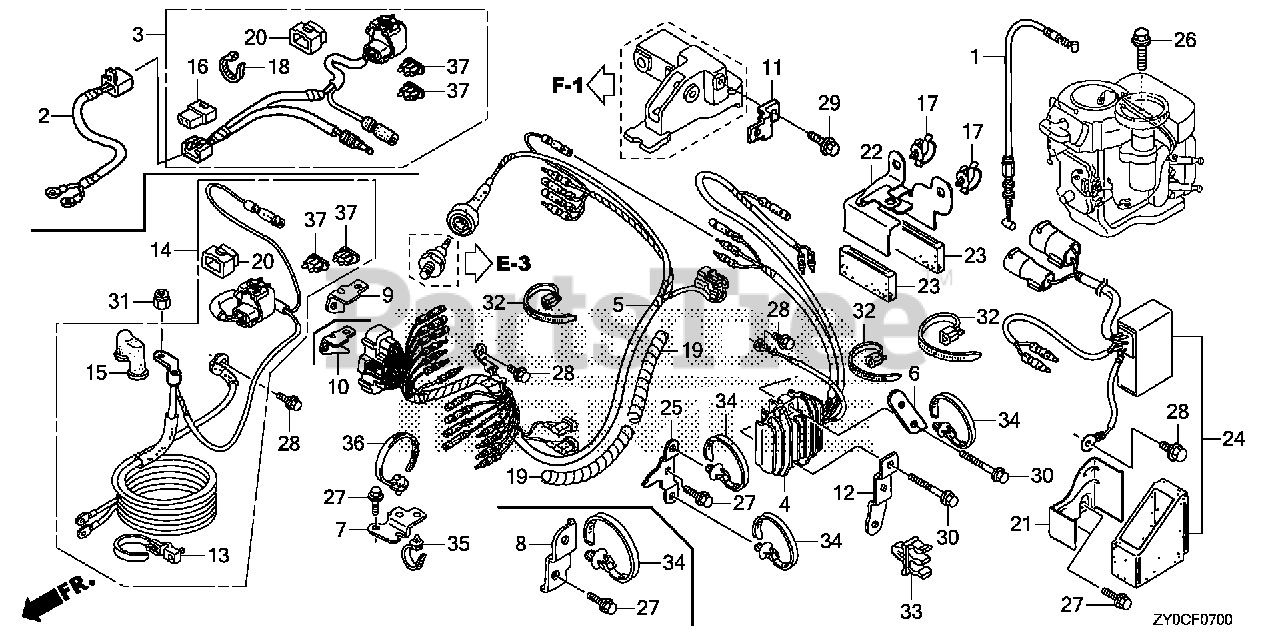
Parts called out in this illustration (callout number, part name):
1	CABLE, NEUTRAL STARTING
4	RECTIFIER ASSY., REGULATOR
5	WIRE HARNESS ASSY. (SELF STARTER)
6	BRACKET, CLIP F
7	BRACKET, STARTER CABLE
10	BRACKET, FUSE CASE (PT)
12	BRACKET, E-CLIP
13	BAND, WIRE
14	CABLE ASSY., STARTER (PT)
15	COVER, MAGNETIC SWITCH TERMINAL
17	CLAMP, WIRE
19	TUBE, SPIRAL A
20	COVER ASSY., FUSE (20A)
21	BRACKET, RELAY (PT)
22	BRACKET, CONNECTOR A
23	GROMMET, CONNECTOR
24	RELAY ASSY., POWER TILT
25	BRACKET, HARNESS CLIP
26	BOLT, FLANGE (6X20)
27	BOLT, FLANGE (6X14) (CT200)
28	BOLT, FLANGE (6X12)
30	BOLT, FLANGE (6X26) (CT200)
31	NUT, LOCK (6MM)
32	TIE, CABLE
33	CLIP, FUEL TUBE
34	CLIP, HARNESS BAND (151.5MM) (NATURAL)
35	BAND, WIRE HARNESS (123.5MM) (BLUE)
36	BAND, WIRE HARNESS (93.5MM) (WHITE)
37	FUSE, BLADE (20A)
